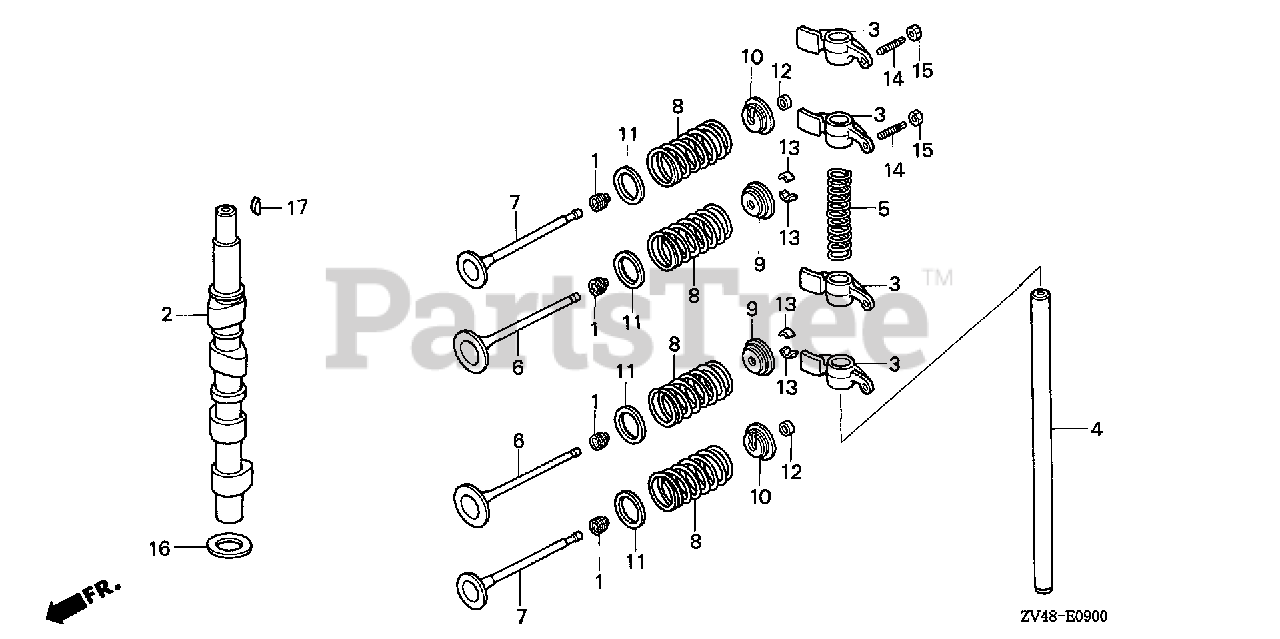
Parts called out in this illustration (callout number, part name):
1	SEAL, VALVE STEM
3	ARM, VALVE ROCKER
4	SHAFT, VALVE ROCKER ARM
5	SPRING, VALVE ROCKER ARM
6	VALVE, IN.
7	VALVE, EX.
8	SPRING, VALVE
9	RETAINER, VALVE SPRING
10	RETAINER, EX. VALVE SPRING
11	SEAT, VALVE SPRING
12	ROTATOR, VALVE
13	COTTER, VALVE (SANKO)
14	SCREW, TAPPET ADJUSTING
15	NUT, TAPPET ADJUSTING
16	WASHER, THRUST (16MM)
17	KEY, WOODRUFF (16X12)
